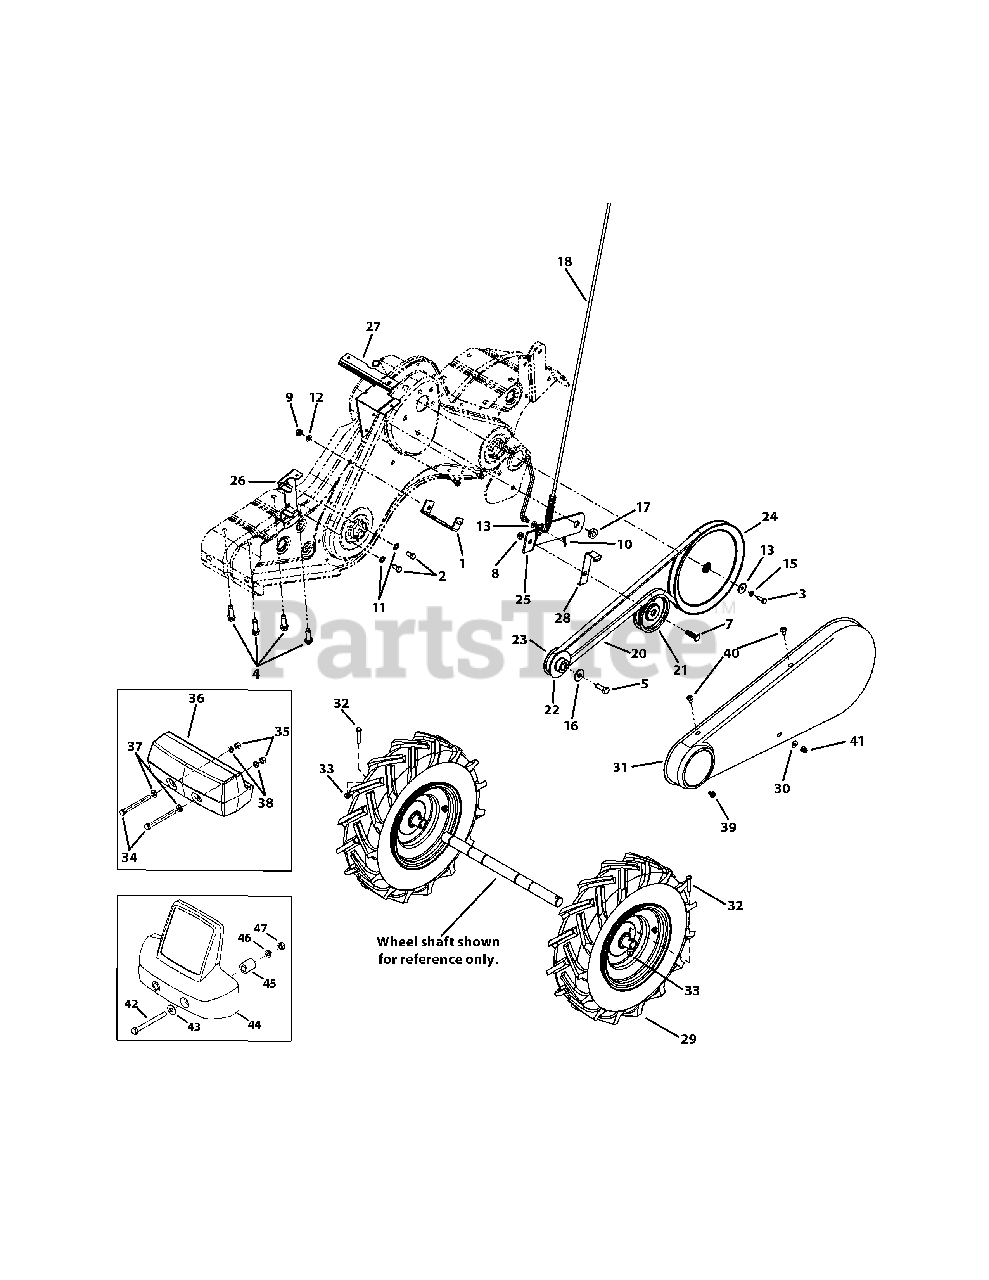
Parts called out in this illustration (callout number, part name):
1	Belt Cover Bracket Assembly
2	Hex Bolt, 5/16-24 x .62"
3	Hex Bolt, 1/4-28 x .75"
4	Hex Washer Screw, 3/8-16 x 1.50"
5	Hex Bolt, 3/8-24 x 1.0
7	Hex Cap Screw, 3/8-16 x 1.25
8	Lock Jam Nut, 3/8-16
9	Hex Nut, 5/16-18
10	Internal Cotter Pin
11	Hairpin Clip
12	Lock Washer, 5/16"
13	Flat Washer, .25 ID x .93 OD
15	Lock Washer, 1/4" ID
16	Bell Washer, .396 ID x 1.14 OD
17	Shoulder Nut, 7/16-20
18	Clutch Cable
21	Flat Idler w/ Flange, 3.75 OD
22	Outer Engine Pulley Half
23	Inner Engine Pulley Half
24	Input Pulley
25	Idler Bracket
26	Belt Keeper Bracket
27	Shift Cover Bracket
28	Idler Belt Keeper
29	Wheel Assembly, 16.0 x 4.6 x 8
30	Flat Washer, .271 ID x .630 OD
31	Belt Cover
32	Hex Head Screw, 1/4-20
33	Flange Lock Nut, 1/4-20
34	Hex Bolt, 1/2-13 x 5.0
35	Hex Nut, 1/2-13
36	Counterweight, 40 lbs.
37	Flat Washer
38	Lock Washer, 1/2
39	Hex Screw, 1/4-20 x .375
40	Screw, 1/4-14 x .625
42	Hex Head Screw, 1/2-13 x 5.50
43	Washer, Flat, 1/2 x 1.25 x .100
44	Counterweight
45	Hub, .636 ID x 1.00 OD x .94
46	Washer, Lock, 1/2
47	Hex Nut, 1/2-20
